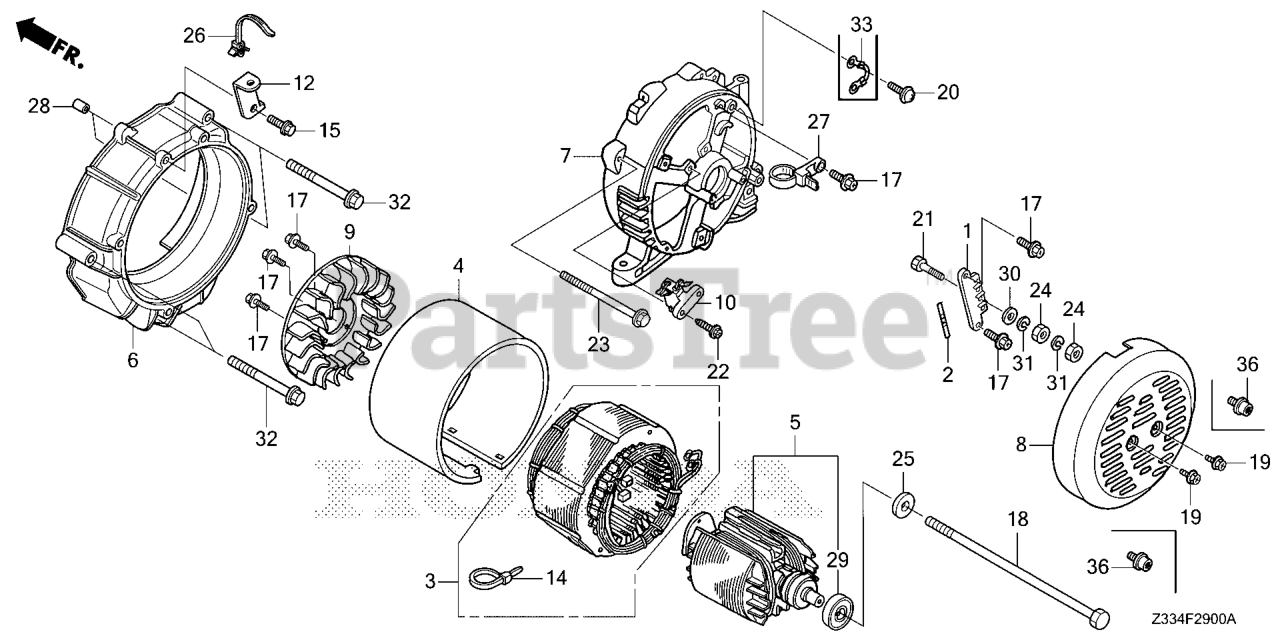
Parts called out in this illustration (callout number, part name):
1	TERMINAL, VOLT CHANGE
2	MARK, VOLT
3	STATOR ASSY.
4	COVER, STATOR *NH105* (MAT BLACK)
6	HOUSING, FR.
7	HOUSING, RR.
8	COVER, GENERATOR END *NH105* (MAT BLACK)
9	FAN, GENERATOR COOLING
10	BRUSH ASSY.
12	BRACKET, WIRE HARNESS CLIP
14	TIE, CABLE (C)
15	BOLT, FLANGE (6X12) (CT200)
17	SCREW, TAPPING (5X14)
18	BOLT, HEX. (10X203)
20	SCREW, PAN (5X12)
21	BOLT, HEX. (5X20)
22	SCREW, TAPPING (5X18)
23	BOLT, FLANGE (6X113)
24	NUT, HEX. (5MM)
25	WASHER (10.5MM)
26	CABLE, STRAP
27	TIE, CABLE
28	PIN, DOWEL (8X12)
29	BEARING ASSY. (6204)
30	WASHER, PLAIN (5MM)
31	WASHER, SPRING (5MM)
32	BOLT, FLANGE (8X60)
36	SCREW, TAPPING (5X12) (TORX)
